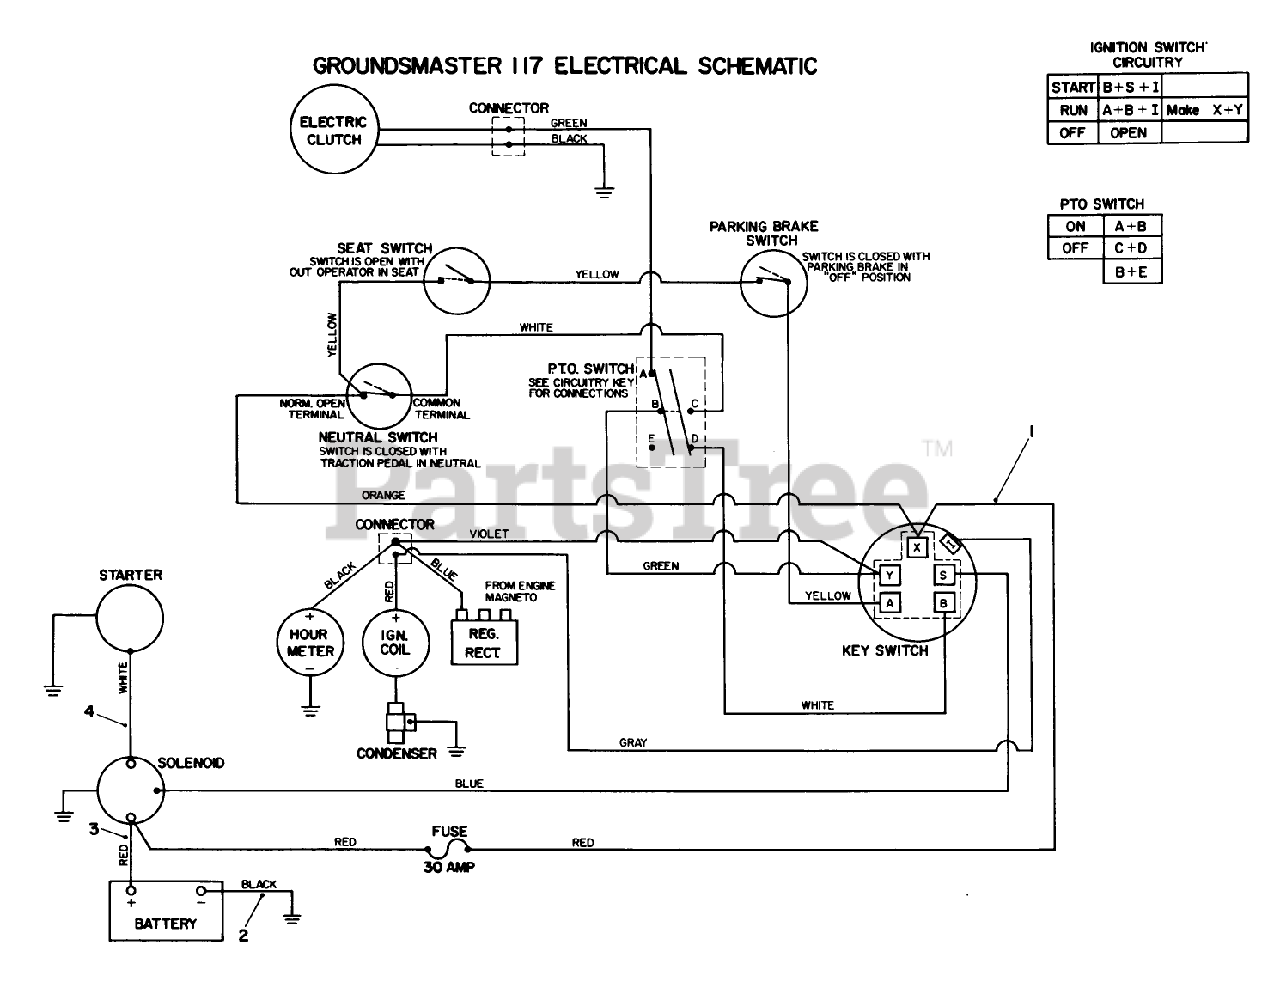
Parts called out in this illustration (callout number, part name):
1	WIRE HARNESS
2	BATTERY/GROUND WIRE
3	WIRE ASM
4	WIRE ASM
